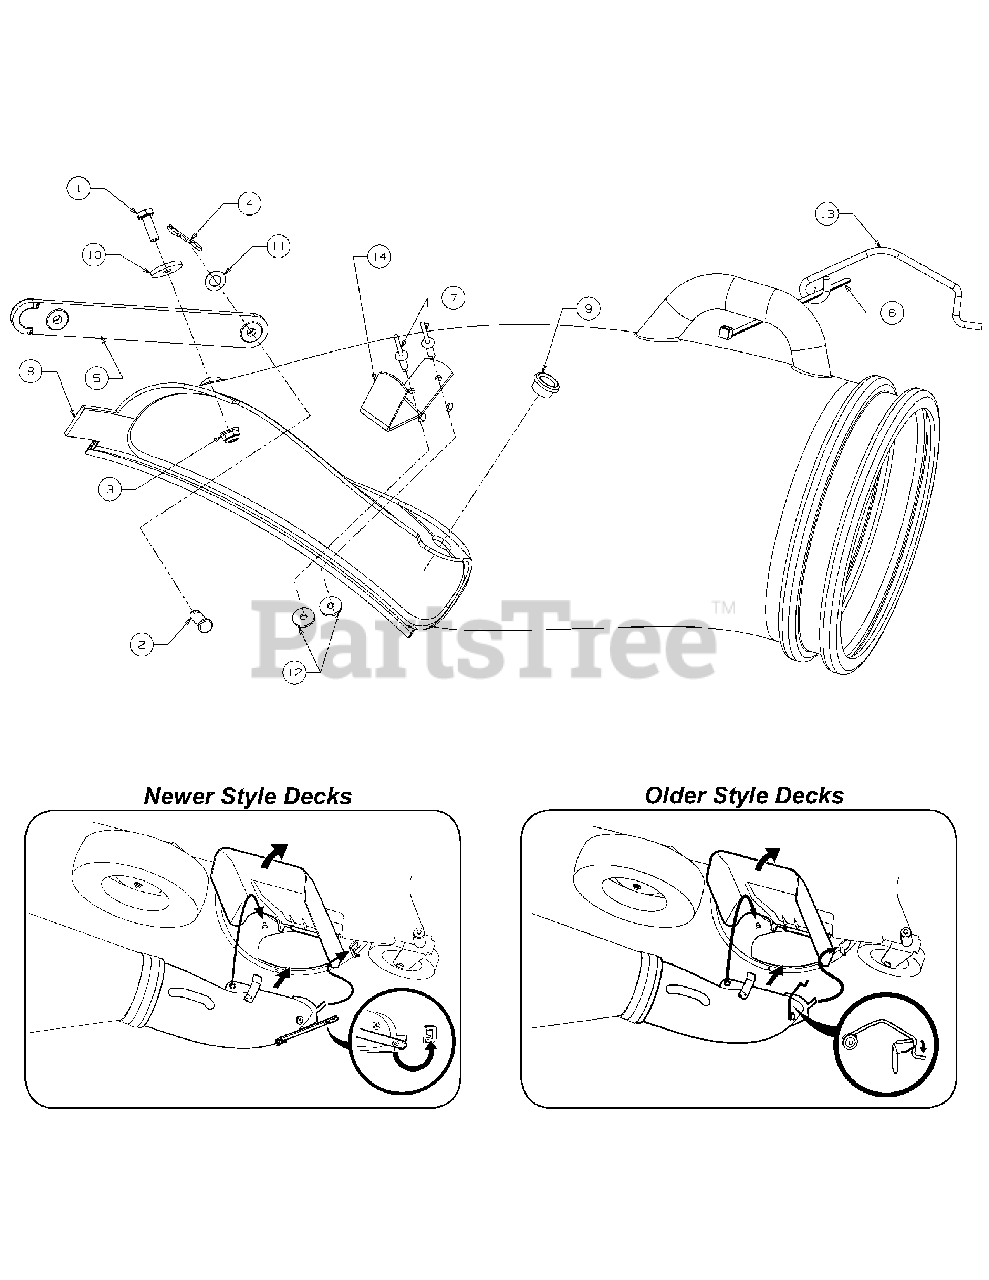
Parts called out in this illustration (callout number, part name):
1	SCREW-HEX 1/4-20X.75 GR5
2	PIN-CLEVIS 5/16 X 3/4
3	NUT-FLGLK
4	PIN-COTTER
5	STRAP-CHUTE
6	TIE-CABLE 7"
7	RIVET:POP .187 DIA
8	CHUT ASM:ELBOW:33"
9	BUSHING-ROD CONTROL
10	WASHER-FL
11	WASHER-FL-.344 ID X .62 OD X .033
12	WASHR-FL .192
